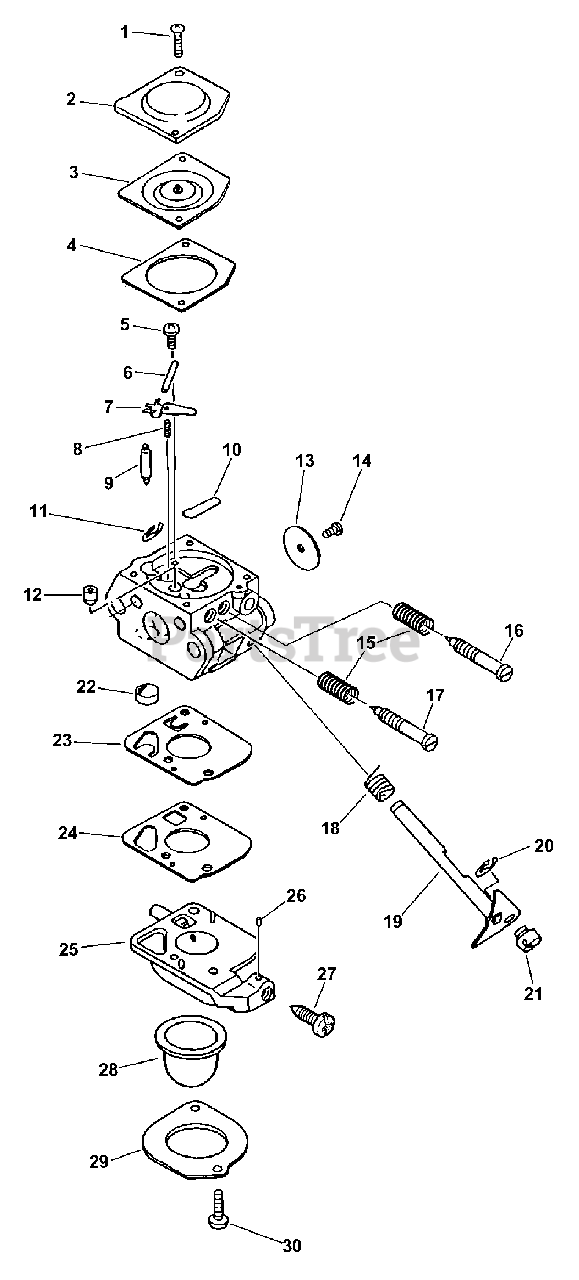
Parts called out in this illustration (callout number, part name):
1	SCREW
2	COVER, METERING
3	DIAPHRAGM
4	GASKET, DIAPHRAGM
5	SCREW, METERING LEVER PIN
6	PIN, METERING LEVER
7	LEVER, METERING
8	SPRING
9	VALVE, NEEDLE
10	PLUG, WELCH
11	RING, RETAINING
12	NOZZLE, CHECK VALVE
13	VALVE, THROTTLE
14	SCREW
15	SPRING
16	NEEDLE - HIGH SPEED
17	NEEDLE - LOW SPEED
18	SPRING, RETURN
19	SHAFT, THROTTLE
20	RING, RETAINING
21	SWIVEL
22	STRAINER
23	DIAPHRAGM, PUMP
24	GASKET, PUMP
25	BASE, PURGE
26	PIECE, FRICTION
27	SCREW, IDLE ADJUST
28	BULB, PURGE
29	RETAINER, PURGE BULB
30	SCREW, RETAINER
